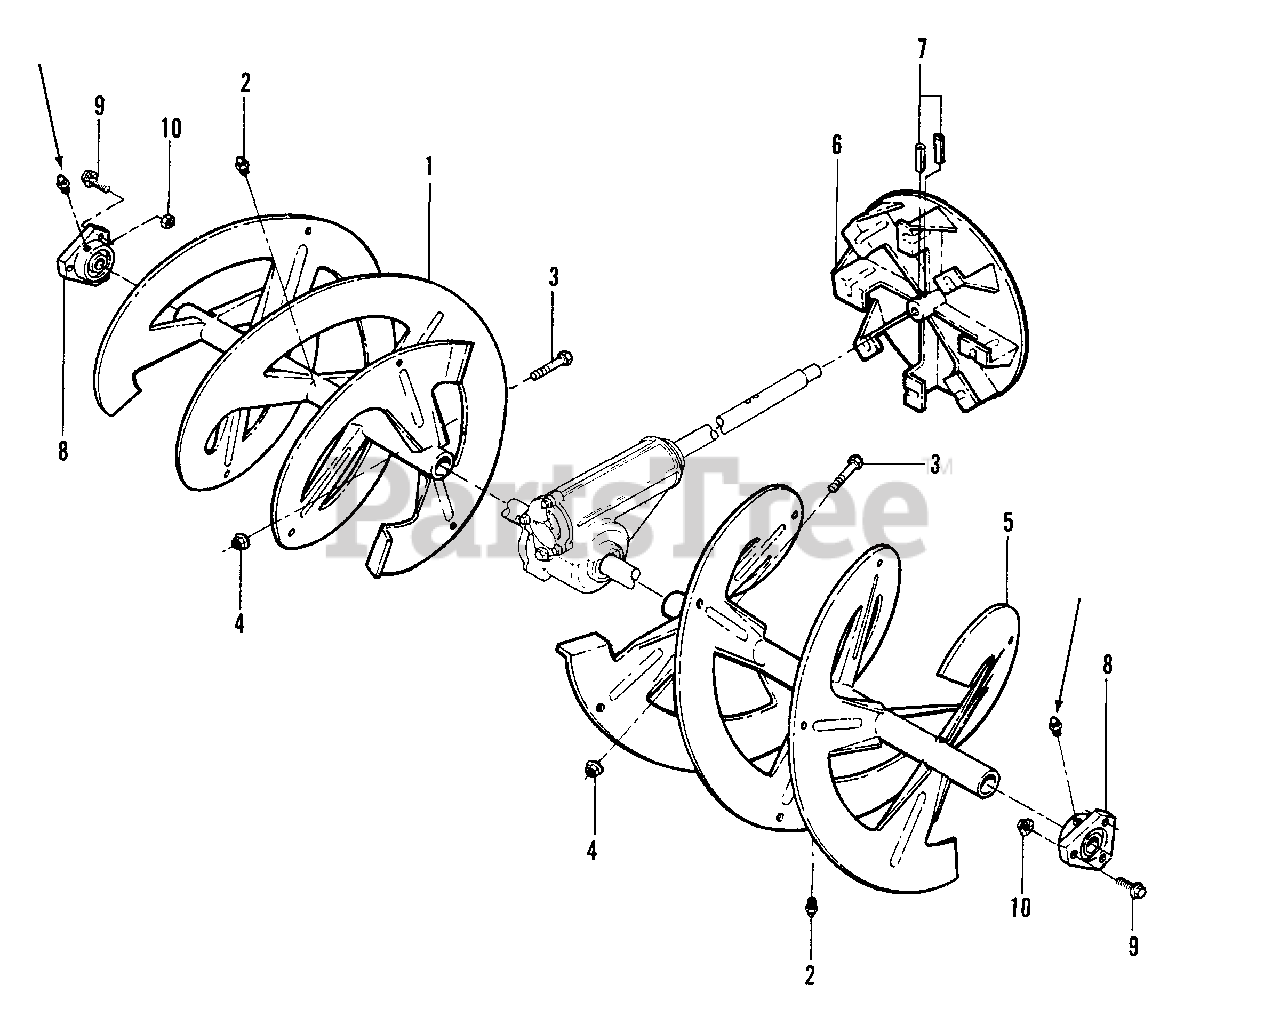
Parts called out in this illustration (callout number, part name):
1	AUGER, Right Side
2	LUBE FITTING, Straight (press-fit for .187 dia. Hole)
3	BOLT, 5/16-18 x 1-7/8" Shear
4	NUT, 5/16-18 Hex Flange Lock
5	AUGER, Left Side
6	FAN, Impeller
7	PIN, Drive Lock
8	BEARING, Auger Shaft
9	BOLT, 1/4-20 x 3/4" Hex Flange Lock
10	NUT, 1/4-20 Hex Flange
